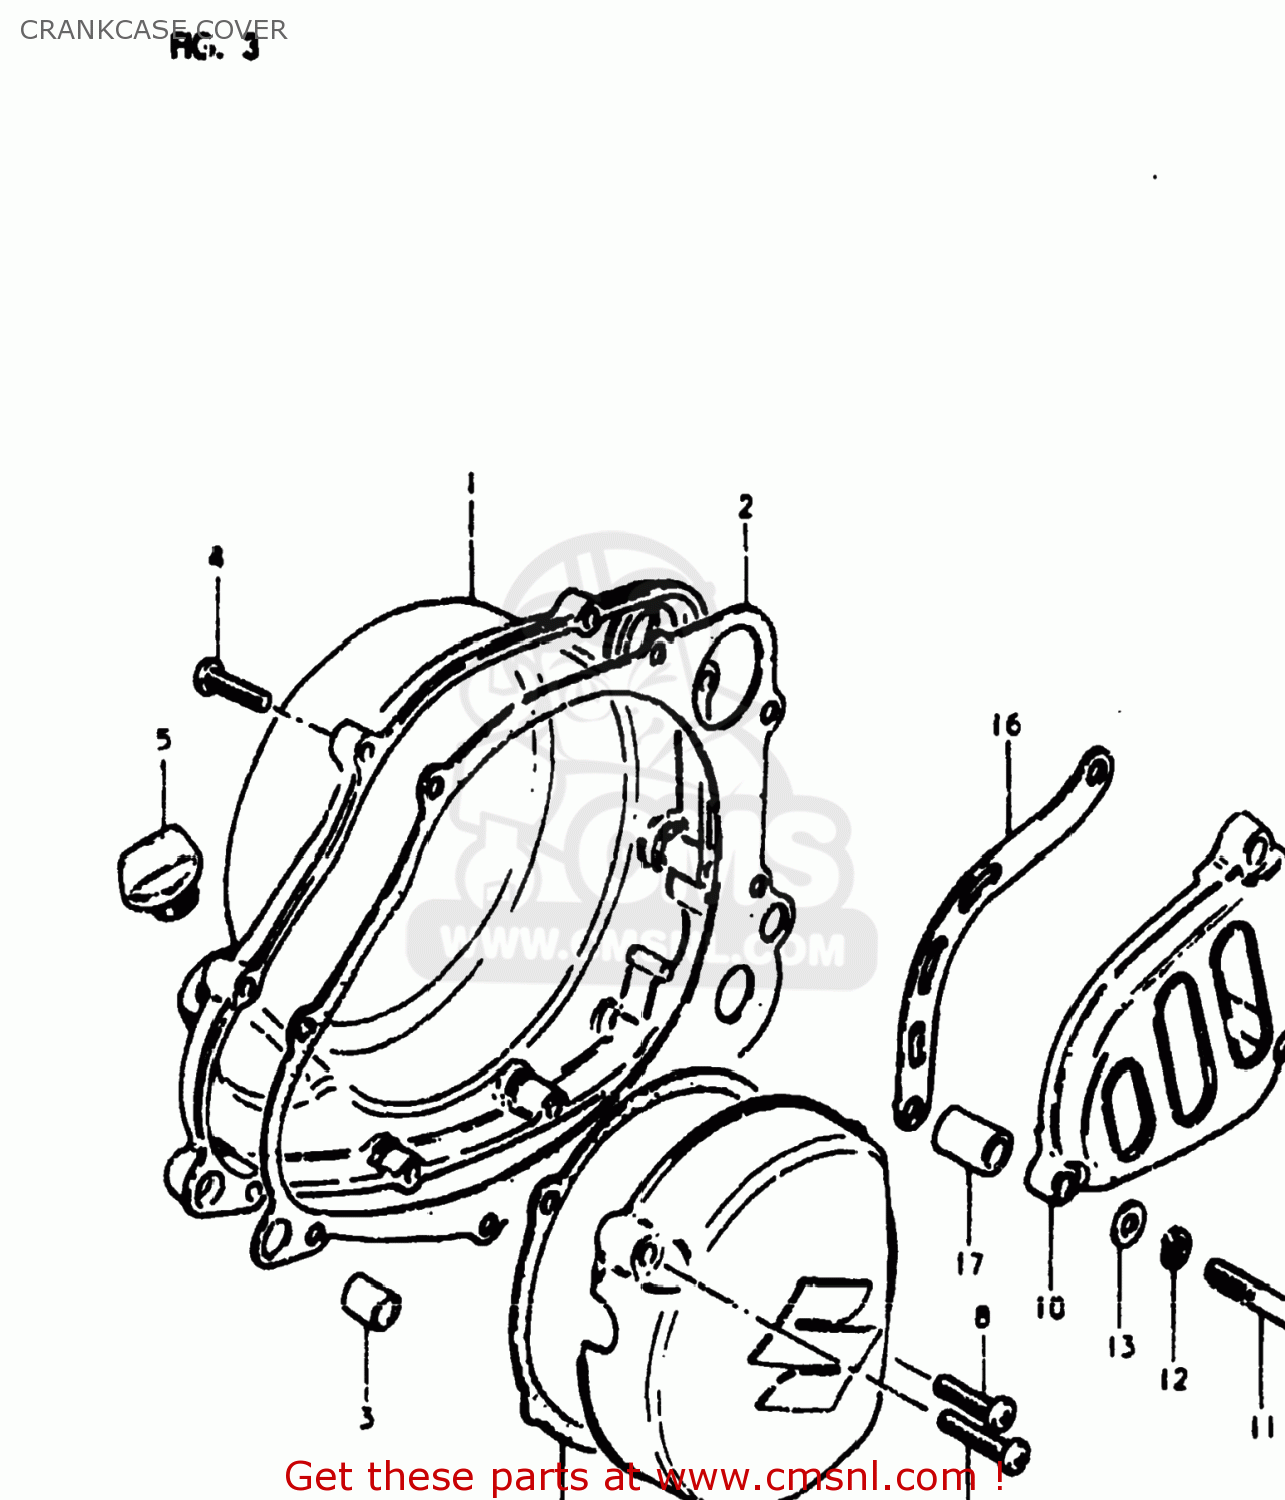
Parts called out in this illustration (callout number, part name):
1	COVER,CLUTCH
2	GASKET,CLUTCH COVER (MCA)
3	PIN
4	SCREW
5	PLUG,OIL FILTER
6	COVER
7	GASKET,MAGNETO COVER (MCA)
8	SCREW
9	SCREW 6X30
10	COVER,ENGINE SPROCKET
11	BOLT 8X55
12	LOCK WASHER
13	WASHER
14	SCREW
15	LOCK WASHER
16	PLATE,FR CHAIN GUIDE
17	SPACER(8.6X16X24)
